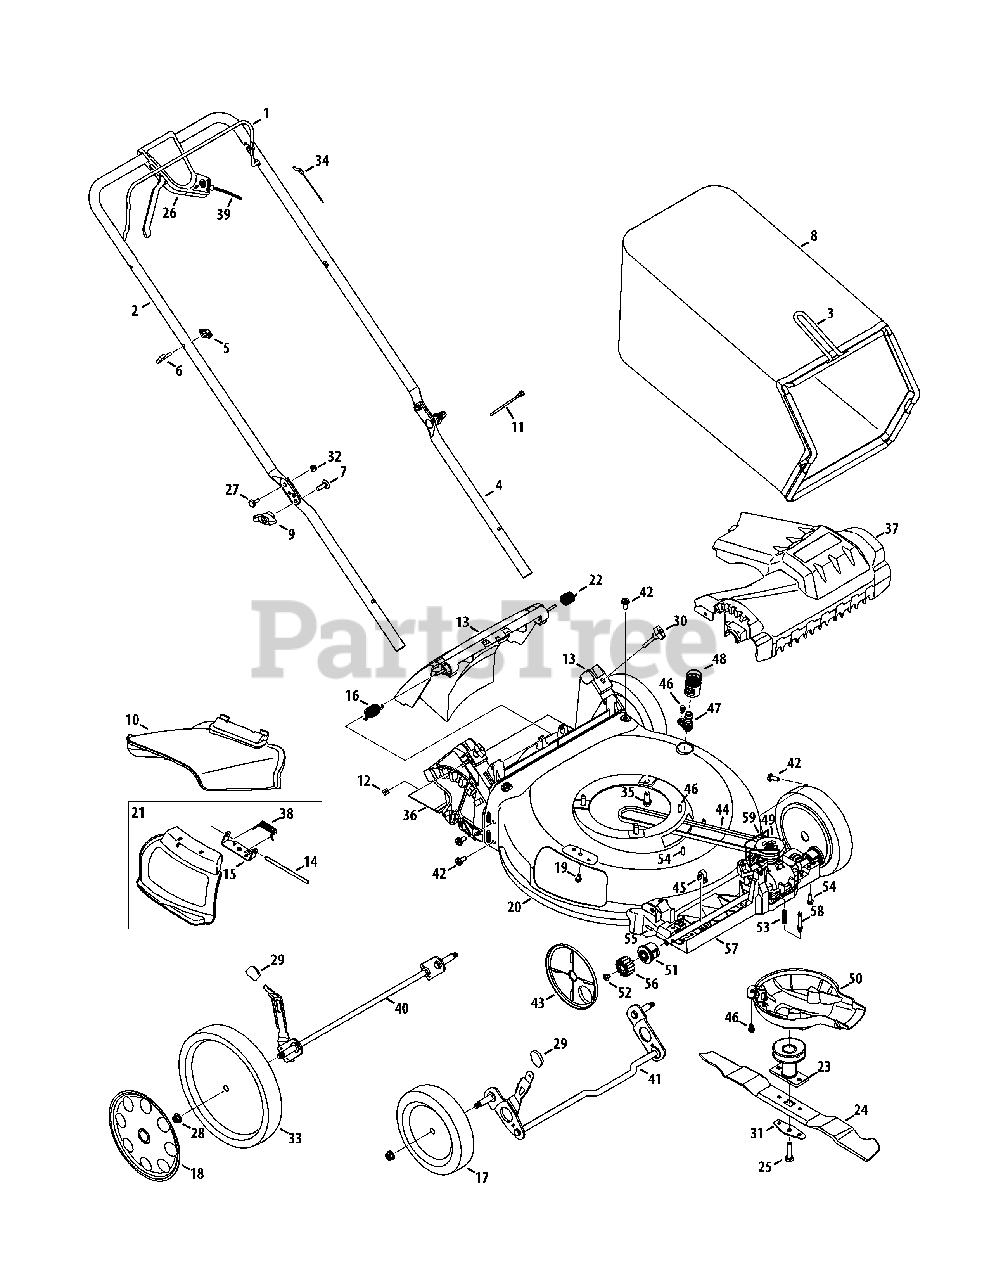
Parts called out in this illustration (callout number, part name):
1	Blade Control
2	Upper Handle
3	Grass Catcher Frame
4	Lower Handle
6	Rope Guide
7	Carriage Screw ,5/16-18
8	Grass Bag
10	Side Chute
11	Cable Tie
12	Nut, Sq., 1/4-20
13	Rear Discharge Door Assembly
13	Rear Discharge Door Assembly (Lowes 766)
15	Chute Deflector Bracket
16	Torsion Spring - RH
17	Front Wheel
19	Screw, 1/4-20 x .500
20	Deck , 21"
21	Hinged Mulch Plug Assembly
22	Torsion Spring - LH
23	Blade Adapter Assembly
24	Mulching Blade
25	Screw , 3/8-24 x 1.50
26	Control Lever Assembly
27	Sldr. Screw, .375 x .126 x 1/4-20
28	Flange Lock Nut, 3/8-16
29	Adjustment Lever Knob
30	Wing Nut
31	Blade Bell Support
32	Nut, Flange Lock, 1/4-20
33	Rear Wheel
34	Control Cable (Honda)
35	TT Sems Screw, 3/8-16 x 1.0
36	Trail Shield
37	Front Cover
38	Torsion Spring
39	Variable Speed Cable
40	Rear Axle Assembly
41	Front Axle Assembly
42	Screw, 5/16-14 x .750
43	Wheel Dust Cover
45	Front Axle Clip
46	Scr., Shldr., 1/4-20 x .50
47	Water Nozzle
48	Water Nozzle Adapter
49	Transmission Assembly
50	Engine Baffle
51	Bearing Assembly
52	Screw, 1/4-20 x .390
53	Compression Spring
54	Screw, 1/4-15 x .750
56	Spur Gear, 14T - RH
56	Spur Gear, 14T - LH
57	Lower Tray
58	Spring Body
59	Transmission Wire
